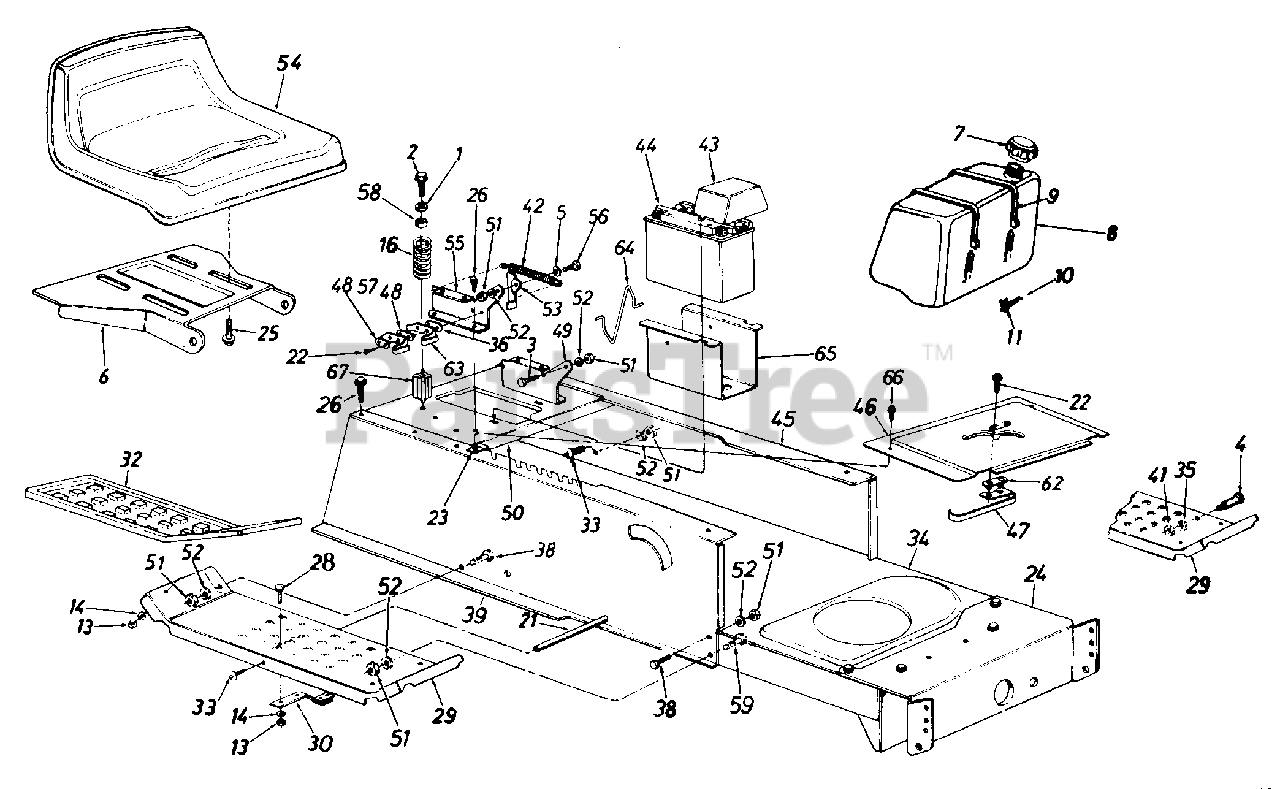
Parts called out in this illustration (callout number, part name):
1	Fl-Wash. .344" I.D. x .875"
2	Hex Wash. Hd. Tap Scr. 5/16-18 x 3.25" Lg.
3	Shld. Bolt .437" Dia. x .162"
4	Shld. Bolt .50" Dia. x .84"
5	Spr-Wash. .445" I.D. x .75
6	Seat Pivot Bracket
7	Fuel Cap
8	Fuel Tank
9	Tie Strap
10	Fuel Line
11	Hose Clamp
13	Hex Nut 1/4-20 Thd.
14	L-Wash. 1/4" I.D.
16	Compression Spring
21	Running Board Rod
22	Hex Wash. Hd. AB-Tap Scr. #8 x .50" Lg.
23	Speed Nut #10Z
24	Front Pivot Brkt.
25	Hex Tap Scr. 3/8-16 x .75"
26	Hex Wash. Hd. AB-Tap Scr. 5/16 x .75" Lg.
28	Carriage Bolt 1/4-20 x .62"
29	Running Board
30	Blade Brake Ass'y.
32	Rubber Foot Pad L.H.
33	Truss Mach. Scr. 5/16-18 x .75" Lg.
34	Lower Frame
35	L-Wash. 3/8" I.D.
36	Insulator Boss Plate
38	Hex Bolt 5/16-18 x .75" Lg.
39	Upper Frame R.H.
41	Hex Nut 3/8-16 Thd.
42	Extension Spring 5.31" Lg.
43	Battery Cover
44	12-V Battery
45	Upper Frame L.H.
46	Shift Cover
47	Reverse Safety Switch
48	Insulator Plate
52	L-Wash. 5/16" I.D.
53	Seat Lift Brkt.
54	Seat
56	Shld. Bolt .437" Dia. x .268"
57	Spring Switch
58	Bushing
59	Hex Wash. TT-Tap Scr. 5/16-18 x 7/8" Lg.
62	Insulator Nut Plate
63	Safety Switch (Seat)
64	Battery Tray Clip
65	Battery Tray
66	Truss Mach. B-Tap Scr. #10 x .5" Lg.
67	Spring Spacer
